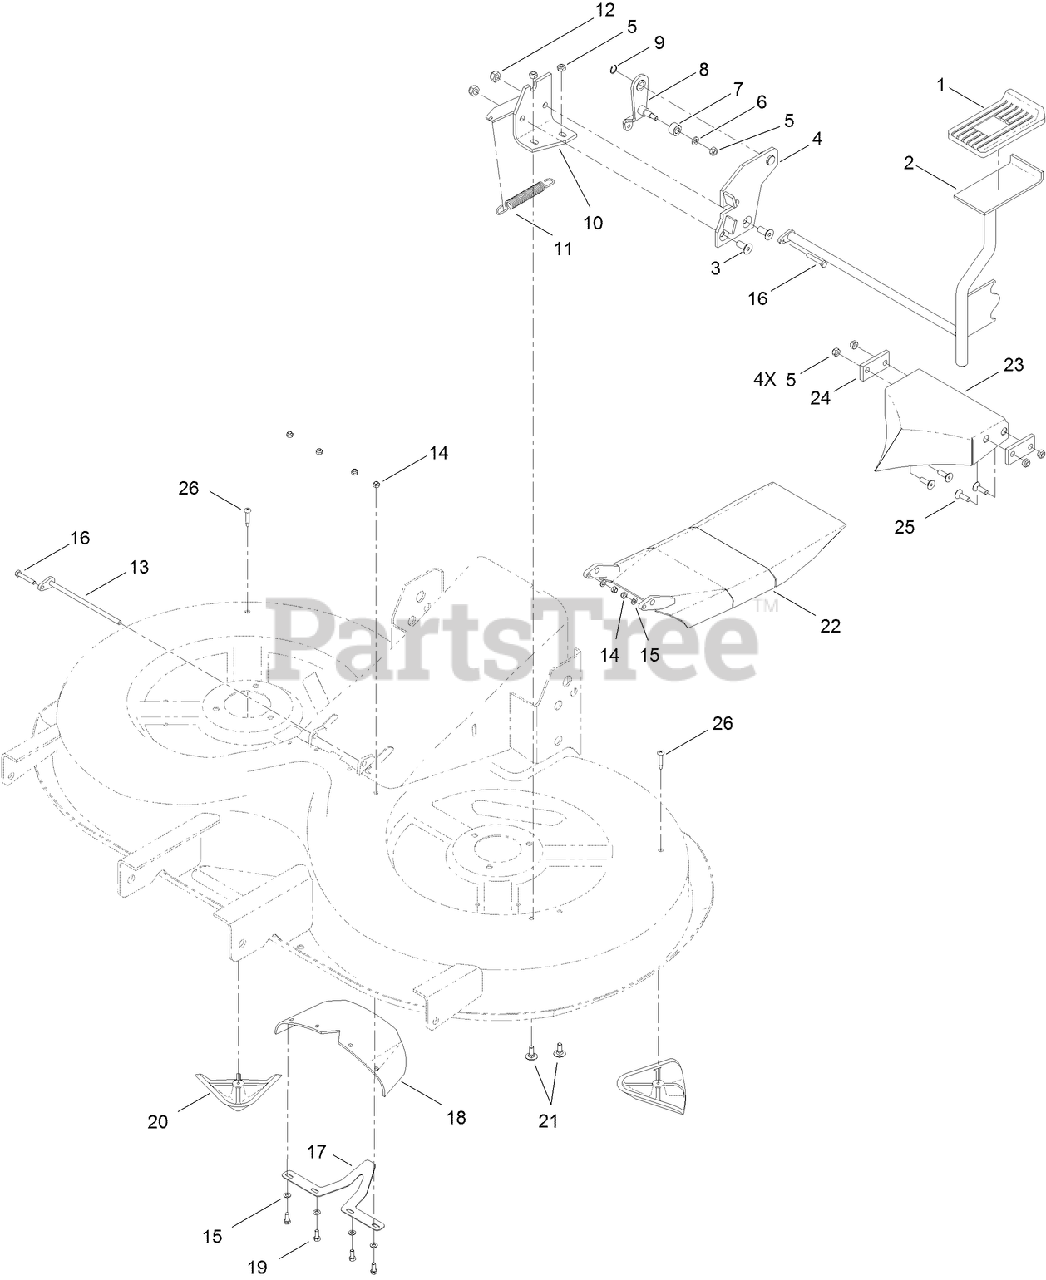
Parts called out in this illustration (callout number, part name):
1	Cover-Lever, FOOT
2	Lever-Foot
3	SCREW-HSFH
4	Plate-Stop
5	NUT-LOCK
6	WASHER-FLAT
7	Roller
8	Lever-Spring
9	RING-LOCKING
10	Bracket-Mounting
11	Spring
12	NUT
13	Rod-Door, Mulch
14	NUT-LOCK
15	WASHER
18	Gasket-Door, Mulch
19	Screw-HH
20	Kicker
21	SCREW-CARR
23	Baffle-Center
24	PLATE-BAFFLE, CENTER
26	SCREW-TAP, PPH
